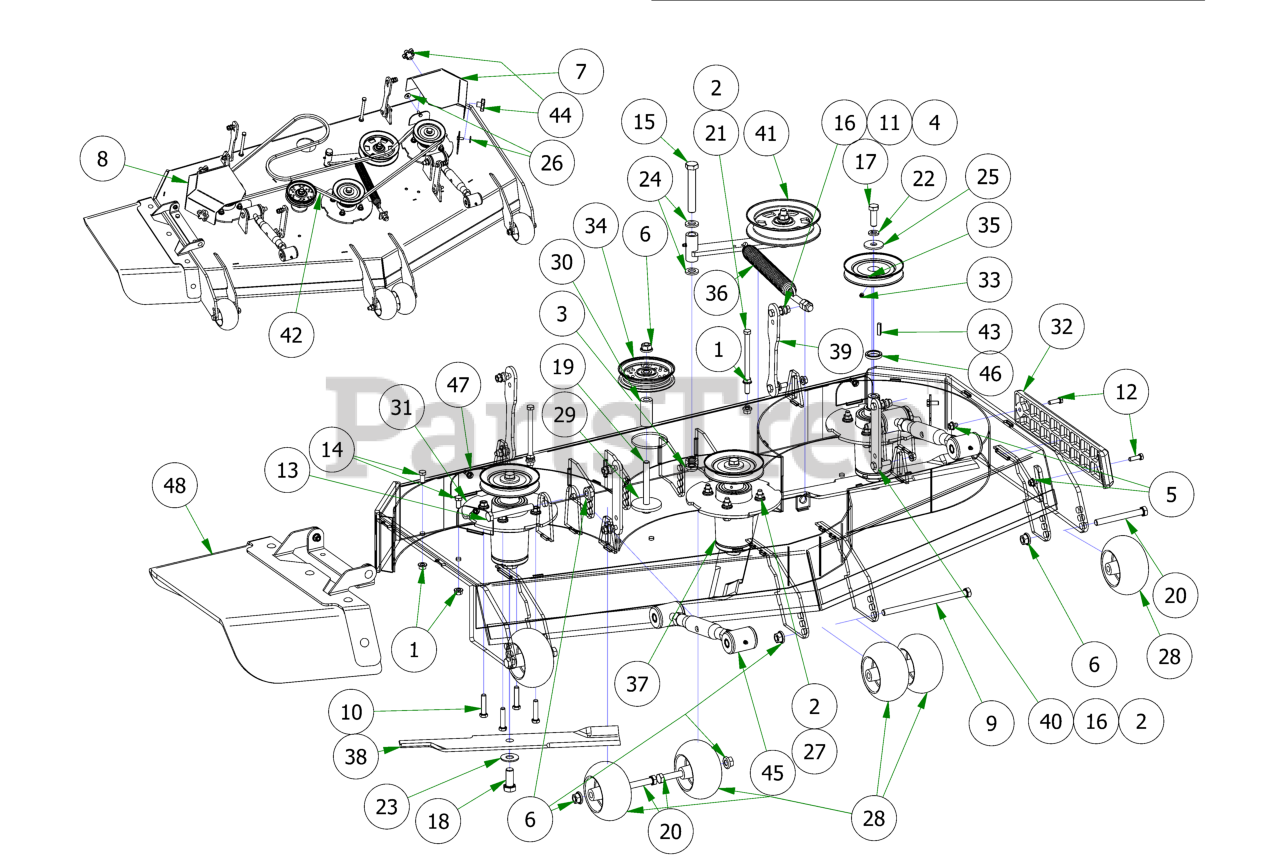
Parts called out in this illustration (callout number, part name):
1	3/8-16 HEX SERRATED FLANGE NUT HARD/ZINC
2	3/8-16 NYLON INSERT FLANGE LOCKNUT (GR.F) ZINC
3	5/8-11 NYLON INSERT JAM LOCKNUT ZINC
4	1/2-13 HEX NUT ZINC
5	5/16-18 NYLON INSERT FLANGE LOCKNUT ZINC
6	1/2-13 NYLON INSERT FLANGE LOCKNUT ZINC
7	2019 Stand On 54" Pulley Cover Trim
8	2019 Stand On 54" Pulley Cover Discharge
9	1/2-13 X 8 HEX CAP SCREW GR 5 ZINC
10	3/8-16 X 1-3/4 HEX C/S (GR.5) ZC
11	All Thread
12	5/16-18 X 1 HEX CAP SCREW (GR.5) ZINC
13	1/2-13 X 4 HEX CAP SCREW (GR.8) ZINC YELLOW
14	3/8-16 X 3/4 HEX CAP SCREW (GR.5) ZINC
15	5/8-11 X 4 HEX CAP SCREW (GR.8) ZINC YELLOW
16	3/8-16 X 1-1/2 HEX CAP SCREW (GR.5) ZINC
17	1/2-20 X 1-1/2 HEX CAP SCREW (GR.5) ZINC
18	5/8-18 X 1-1/2 HEX CAP SCREW (GR.8) ZINC YELLOW
19	1/2-13 X 4-1/4 HEX CAP SCREW (GR.5) ZINC
20	1/2-13 X 4-1/2 HEX CAP SCREW (GR.5) ZINC
21	3/8-16 X 5-1/2 HEX CAP SCREW (GR.5) ZINC
22	1/2 SPLIT LOCKWASHER (GR.8) ZINC/YELLOW
23	5/8 USS FLAT WASHER (1-3/4" OD) GR.8 ZINC YELLOW
24	.635 ID X 1.120 OD X .140 THICK FLAT WASHER NYLON
25	1/2 BELLEVILLE WASHER (1-5/8 OD X .140 THK) ZINC
26	.360 ID X .983 OD X .120 THICK FLAT WASHER NYLON BLACK
27	5/16 USS FLAT WASHER (7/8 OD) ZINC
28	2019 Deck Wheel
29	MZ Deck Idler Spacer
30	2019 Revolt Stationary Idle Spacer
31	Deck Spindle Support Plate
32	REVISED TRIM BUMPER_20180226
33	5/16-24 X 1/4 SOCKET SET SCREW (CUP PT) PLAIN
34	4 3/4 Idler Pulley - ABFI-76
35	5" Spindle Deck Pulley
36	2019 Outlaw Gen2 Deck Spring
37	Spindle Assembly
38	54" Fusion Blade for ZT/Mav/Outlaw/Revolt
39	2019 Stand-On Rear Deck Hanger
40	2019 Revolt Front Deck Hanger
41	2019 Revolt Deck Idler Assembly
42	42 inch Deck Belt- B120
43	1/4 X 1 SQ MACHINERY KEY 1018 STL PLN
44	5/16" Knob
45	Turnbuckle
46	Spacer, 1x1.375x.25
47	2019 Stand On 54" Sloped Deck Welded Assemly
48	2019 Outlaw Gen2 Chute Assembly
